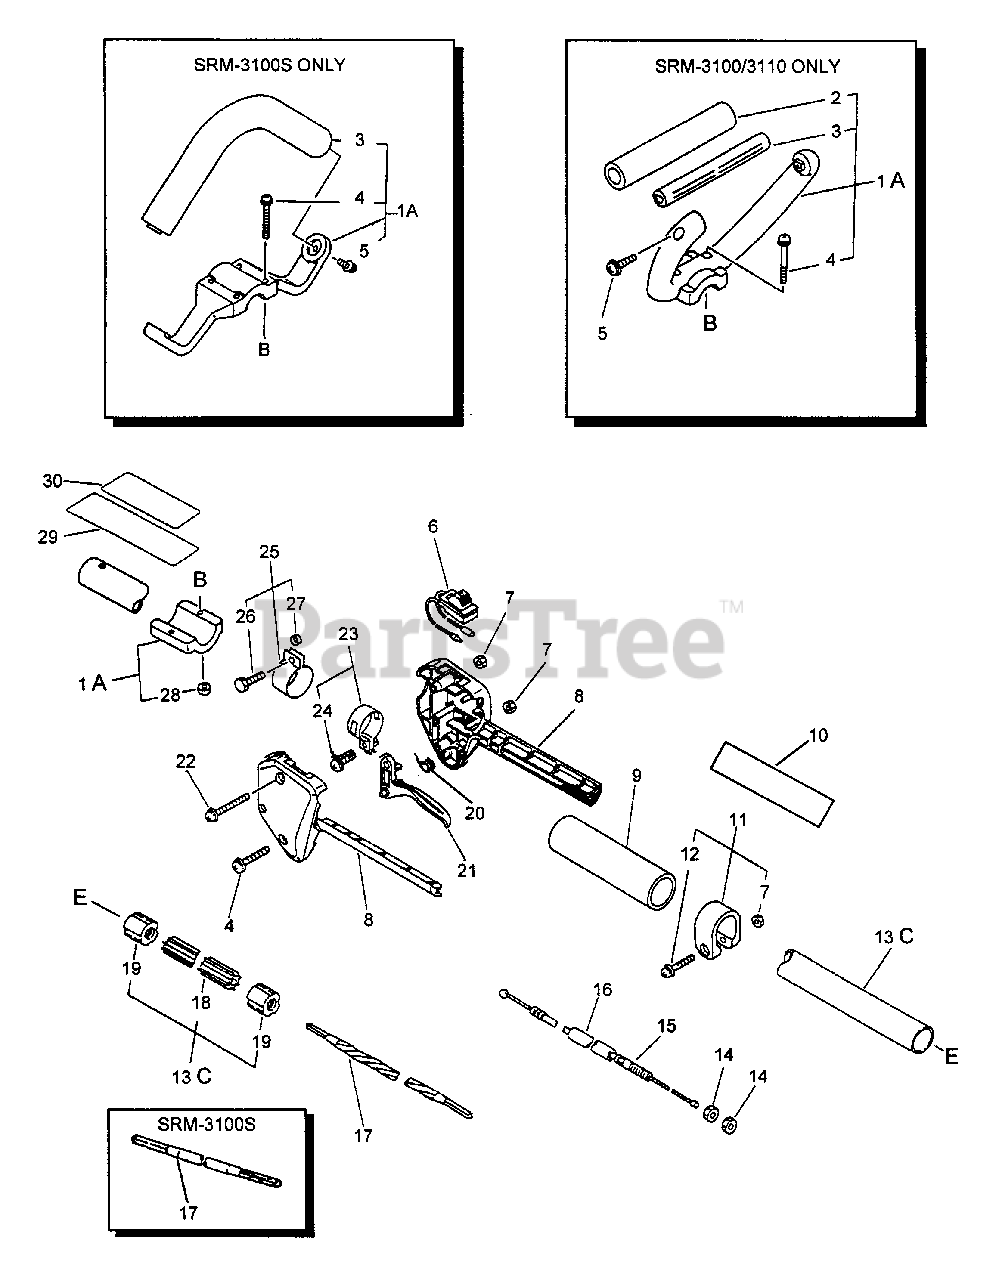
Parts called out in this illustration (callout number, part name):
1	LOOP HANDLE ASSY
2	GRIP, HANDLE
3	HANDLE
3	HANDLE - FRONT
4	SCREW - 5X35
5	SCREW - 5X30
5	SCREW - 5X14
6	IGNITION SWITCH ASSY
8	CONTROL HANDLE KIT
9	GRIP, HANDLE
10	LABEL - ALIGNMENT
11	CLAMP KIT
12	SCREW - 5X28
13	MAIN PIPE ASSY
15	CABLE, THROTTLE
16	TUBE - VINYL
17	DRIVESHAFT - FLEXIBLE
17	DRIVESHAFT - SOLID
18	LINER - FLEXIBLE
20	SPRING, TRIGGER
21	TRIGGER, THROTTLE
22	SCREW - 5X25
23	CLAMP KIT
24	SCREW - 5X14
25	CLAMP
26	BOLT - 5X18
29	LABEL - CAUTION
30	LABEL - CAUTION
